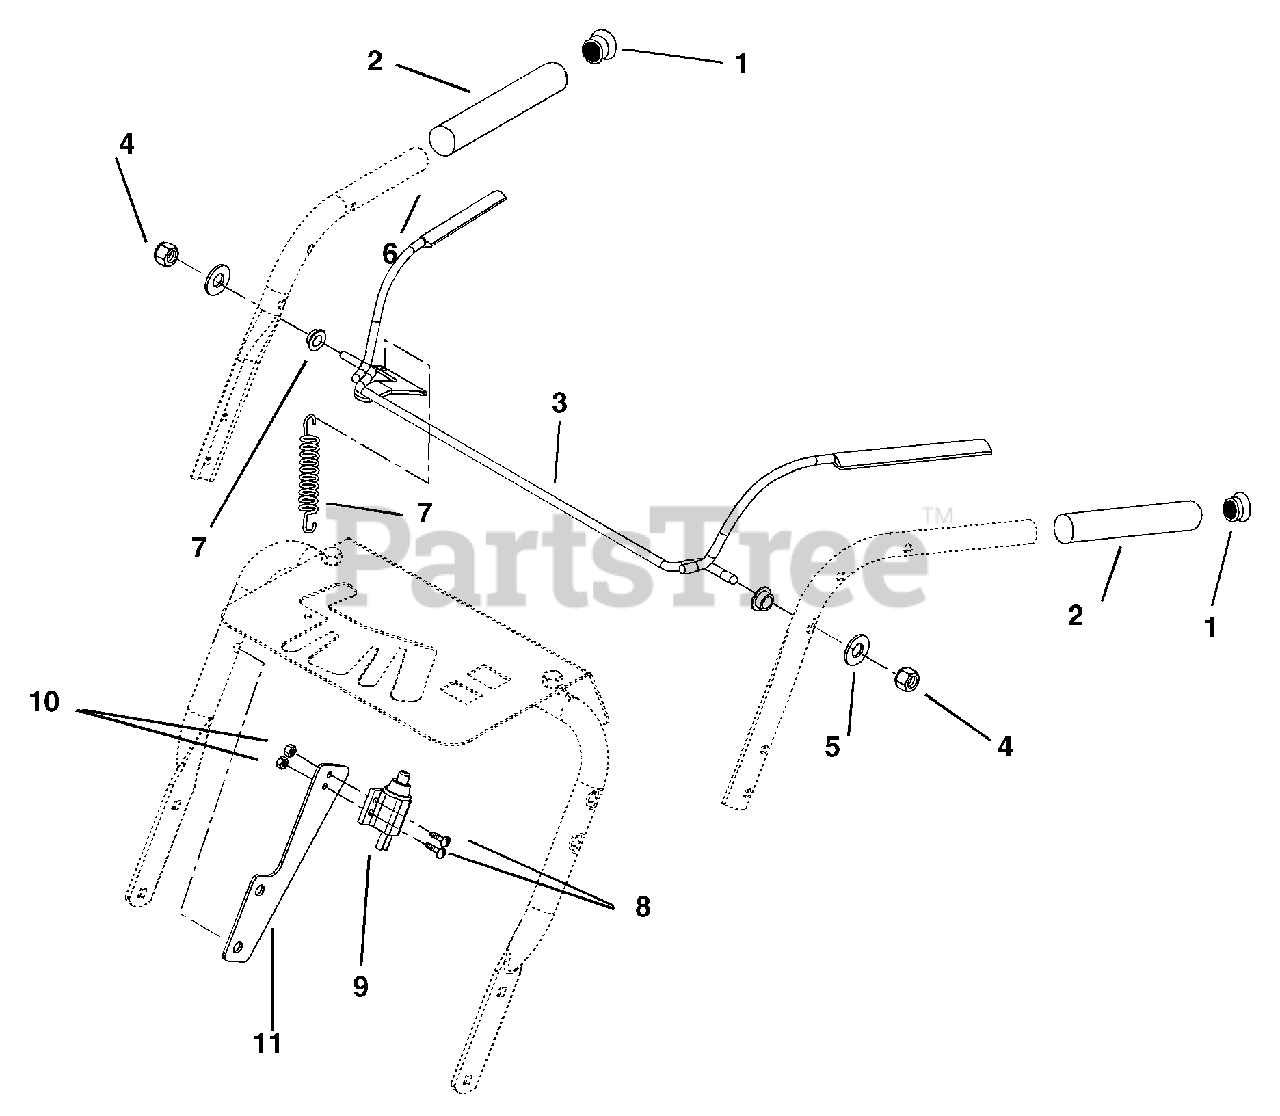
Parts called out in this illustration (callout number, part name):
1	CLOSURE,VINYL
2	GRIP, HANDLE
3	WMT, ROD
4	@NUT-LK-CTR .31-18 YWZC
5	@WSHR-FL-STL.344X.688X.065YWZC
6	BSHG-FLG .325X.444X.440X.560
7	SG-TENS .041X.500X1.750
8	@SCR-MCH 10-24X.75 HWH YWZC
9	SWITCH-SINGLE POLE N.O.W/COVER
10	@NUT-LK-NYL 10-24 W/INSRT YWZC
11	BRACKET, SWITCH MOUNTING
